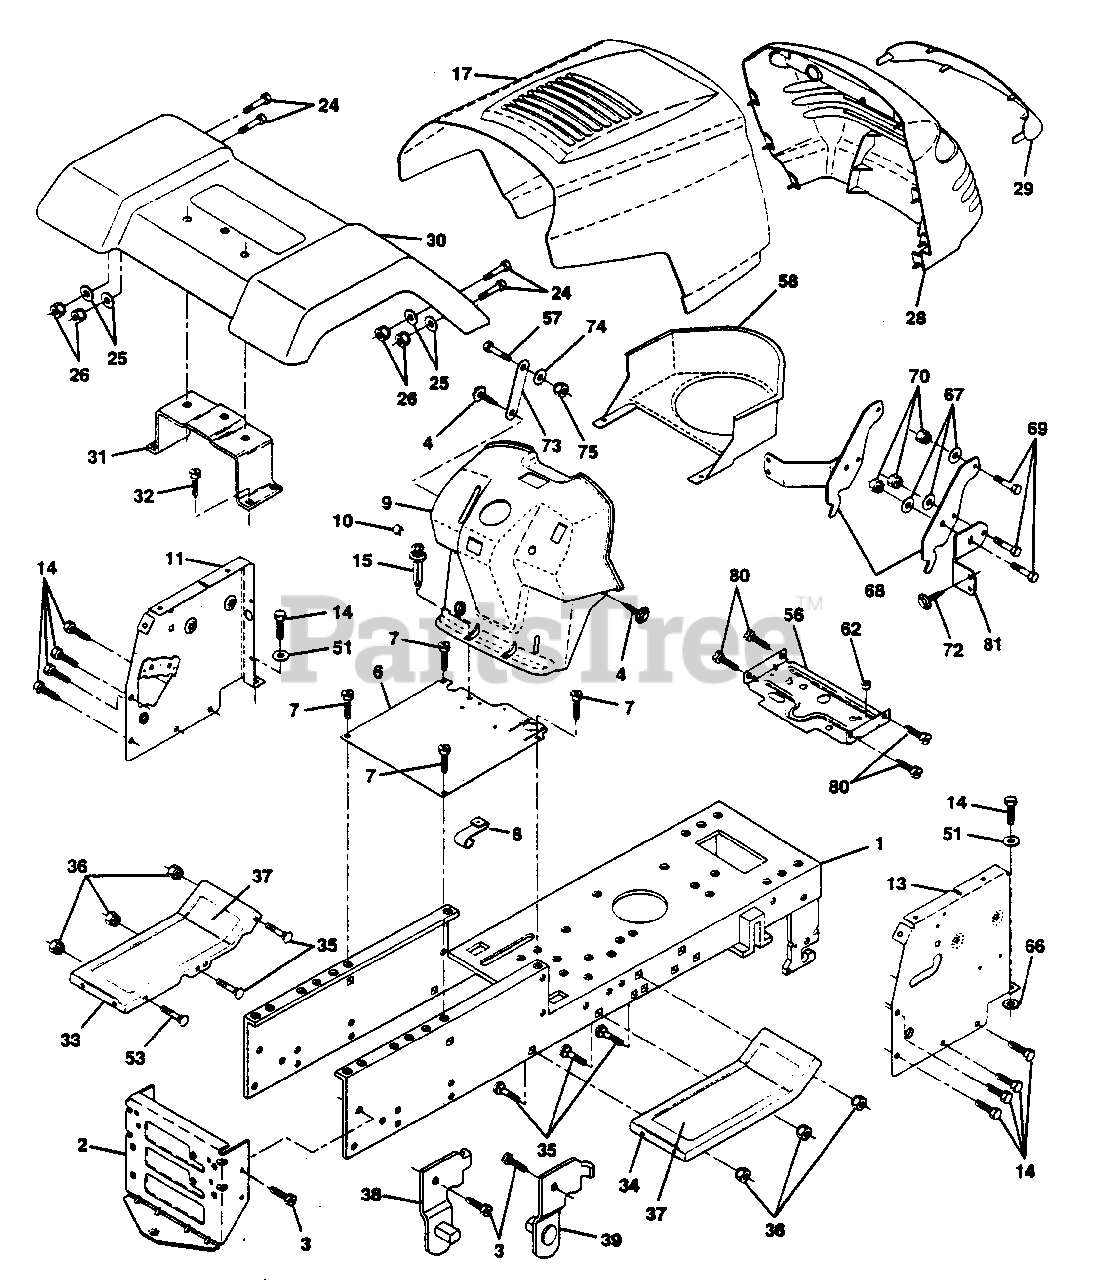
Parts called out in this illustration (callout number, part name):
1	Chassis Weldment 11ga
2	Drawbar, Stretch
3	Screw Thdrol 3/8-16x3/4 Ty-tt
4	Screw Hexwsh. Thdrol 1/4-20 x 3/4
6	Saddle LT Fender Shift
7	Screw Thdrol 3/8-16x3/4 Ty-tt
8	Clip Line Fuel 13/32 Mtg Hole
9	Dash Private Label
11	Panel Pnt Dash Lh
13	Panel Dash Rh Weldment
14	Screw Thdrol 3/8-16x1/2 Ty-tt
17	Hood Paint Steel Private Label
24	Bolt Fin Hex 3/8-16unc X1
25	Washer 13/32 X 13/16 X 12 Ga
26	Nut Lock 3/8-16 Unc
28	Grille Private Label
29	Lens Grille Private Label
31	Bracket Pnt Fender
32	Screw Thdrol 3/8-16x3/4 Ty-tt
33	Footrest Pnt Lh
34	Footrest Pnt Rh
35	Bolt Rdhd Sht Sqnk 3/8-16 X3/4
36	Nut Lock 3/8-16 Unc
38	Bracket, Asm. Pivot, L.H., Mower Rear
39	Bracket, Asm. Pivot, R.H., Mower Rear
51	Washer 13/32 x 3/4 x 16 Ga.
53	Bolt Carriage 3/8-16 x 1
56	Support Battery
57	Screw Hex 1/4-20 x 3/4
58	Air Duct P/L
66	Washer Lock Ext. Tooth 3/8
67	Washer 9/32 x 7/8 x 16 Ga.
68	Hinge Pickoff Hood
69	Bolt Hex Hd 1/4-20
70	Nut, Crownlock 1/4-20
72	Screw Lock Spider #8 x 7/8
73	Brace
74	Washer 9/32 x 7/8 x 16 Ga.
75	Nut Lock Hex W/Ins 1/4-20
80	Screw Thdrol 5/16-18 X3/4
81	Bracket, Grill
